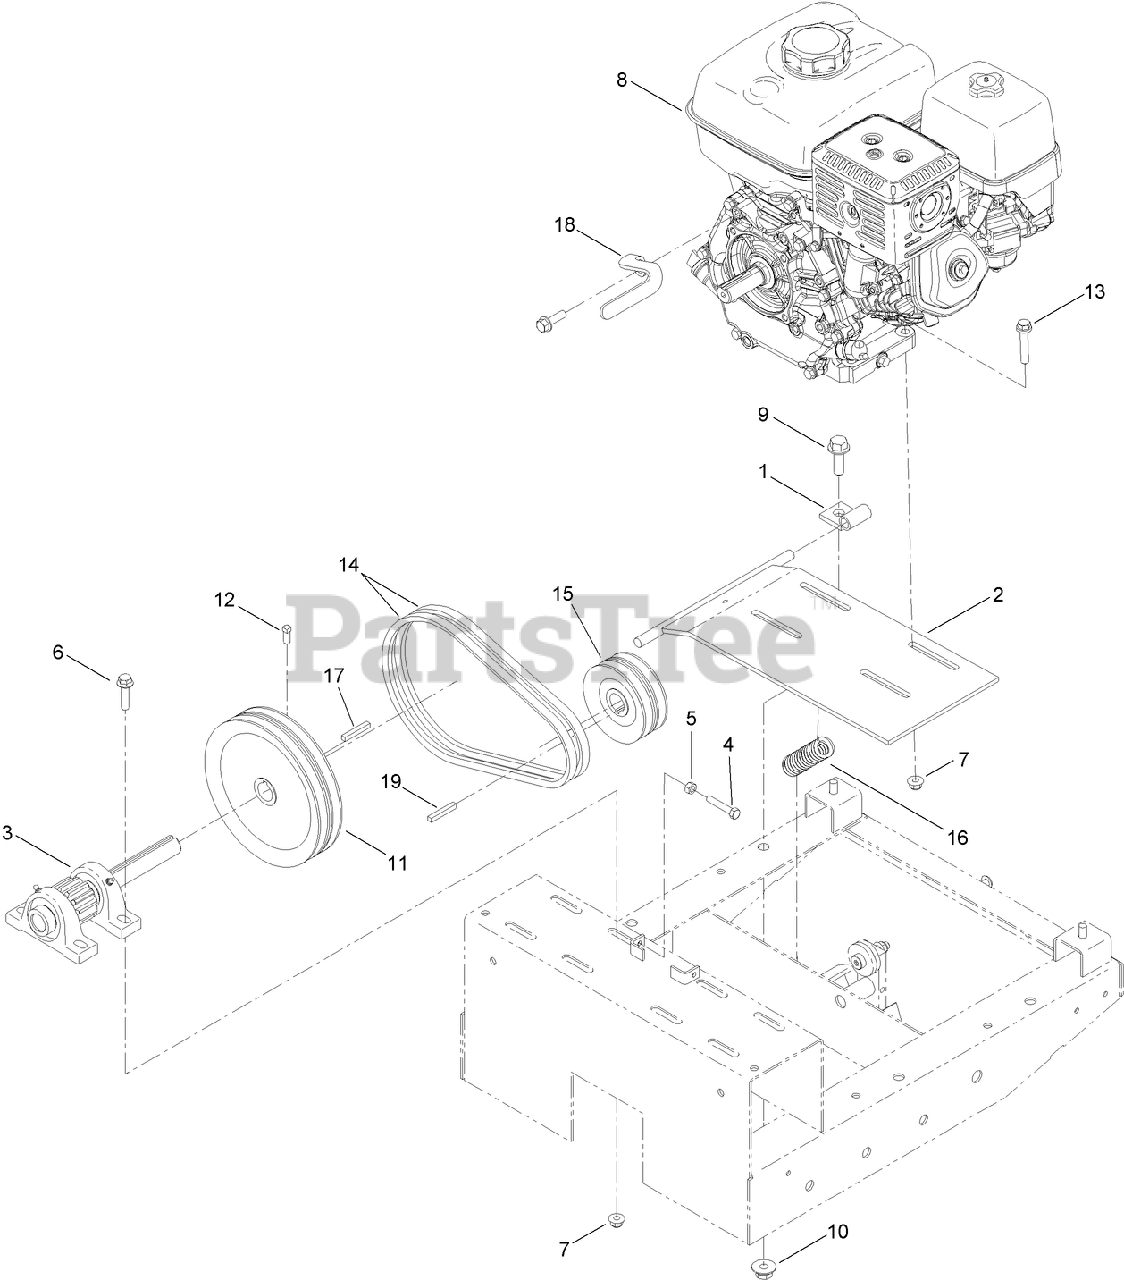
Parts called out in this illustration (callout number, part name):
1	MOUNT-MOTOR
2	BASE-MOTOR
3	PINION ASM
4	SCREW-HH
5	NUT-HEX
6	SCREW-HHF
7	NUT-HF, NI
8	ENGINE-HONDA, GX240
9	SCREW-HHF
10	NUT-HF
11	SHEAVE
12	SCREW-SET, SQH
13	SCREW-HHF
14	BELT-V
15	SHEAVE
16	SPRING
17	KEY-SQUARE
18	GUIDE-BELT
19	KEY-SQUARE
